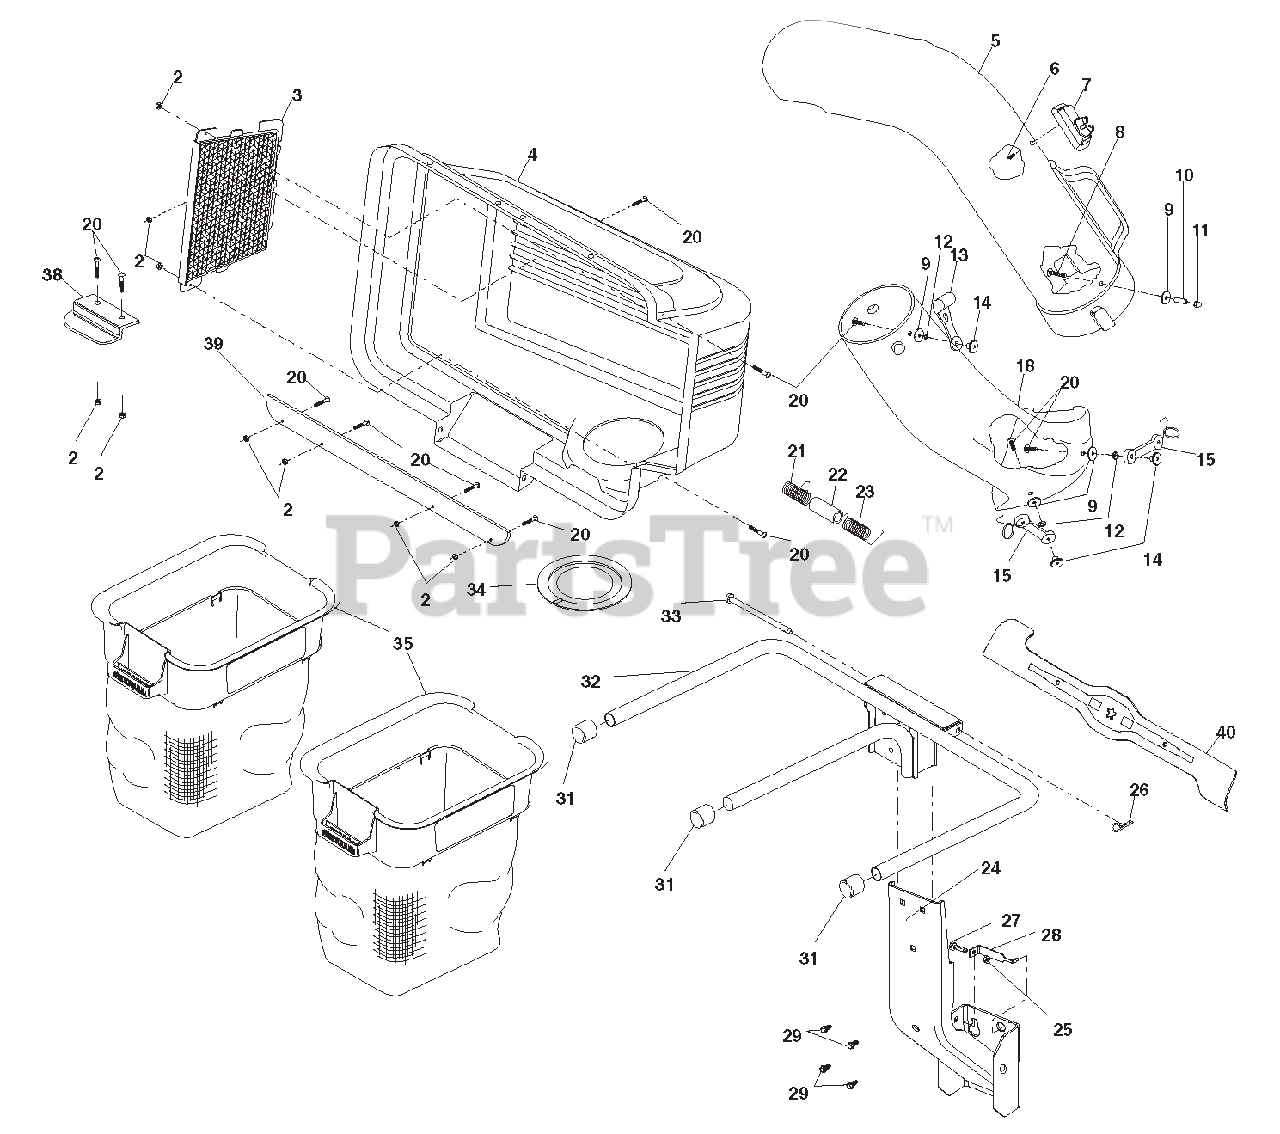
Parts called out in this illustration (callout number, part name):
2	NUT, CROWN LOCK #10-24
3	SCREEN, BAGGER COVER
4	Cover Assembly (Includes 3, 38
5	Chute, Upper
6	Screw, Special #10-14x1/2
7	FULL BAG INDICATROR
8	SCREW #10-24 X 1-1/8"
9	Washer 3/16x3/4x16 Ga.
10	Spacer, Split
11	ACORN NUT #10-24
12	LOCK WASHER
13	CHUTE LATCH, HUSQ BAGGER
14	Nut, Weld
15	Latch Hook
18	CHUTE, LOWER
20	Screw #10-24 x 5/8
21	Spring, Cover L.H. (black)
22	Spacer, Cover
23	Spring, Cover R.H. (gray)
24	Support Assemble
25	Lock Nut 1/4-20
26	RETAINER.SPRING
28	Bracket, Lock
29	Bolt, Shoulder 5/16-18
31	Plug, Tubing End
32	Bagger, Frame
33	Pin, Hinge
34	GASKET, BAGGER COVER
35	Container
38	Latch Handle, Cover
39	Strip, Reinforcement
40	BLADE, 30" BAGGER
